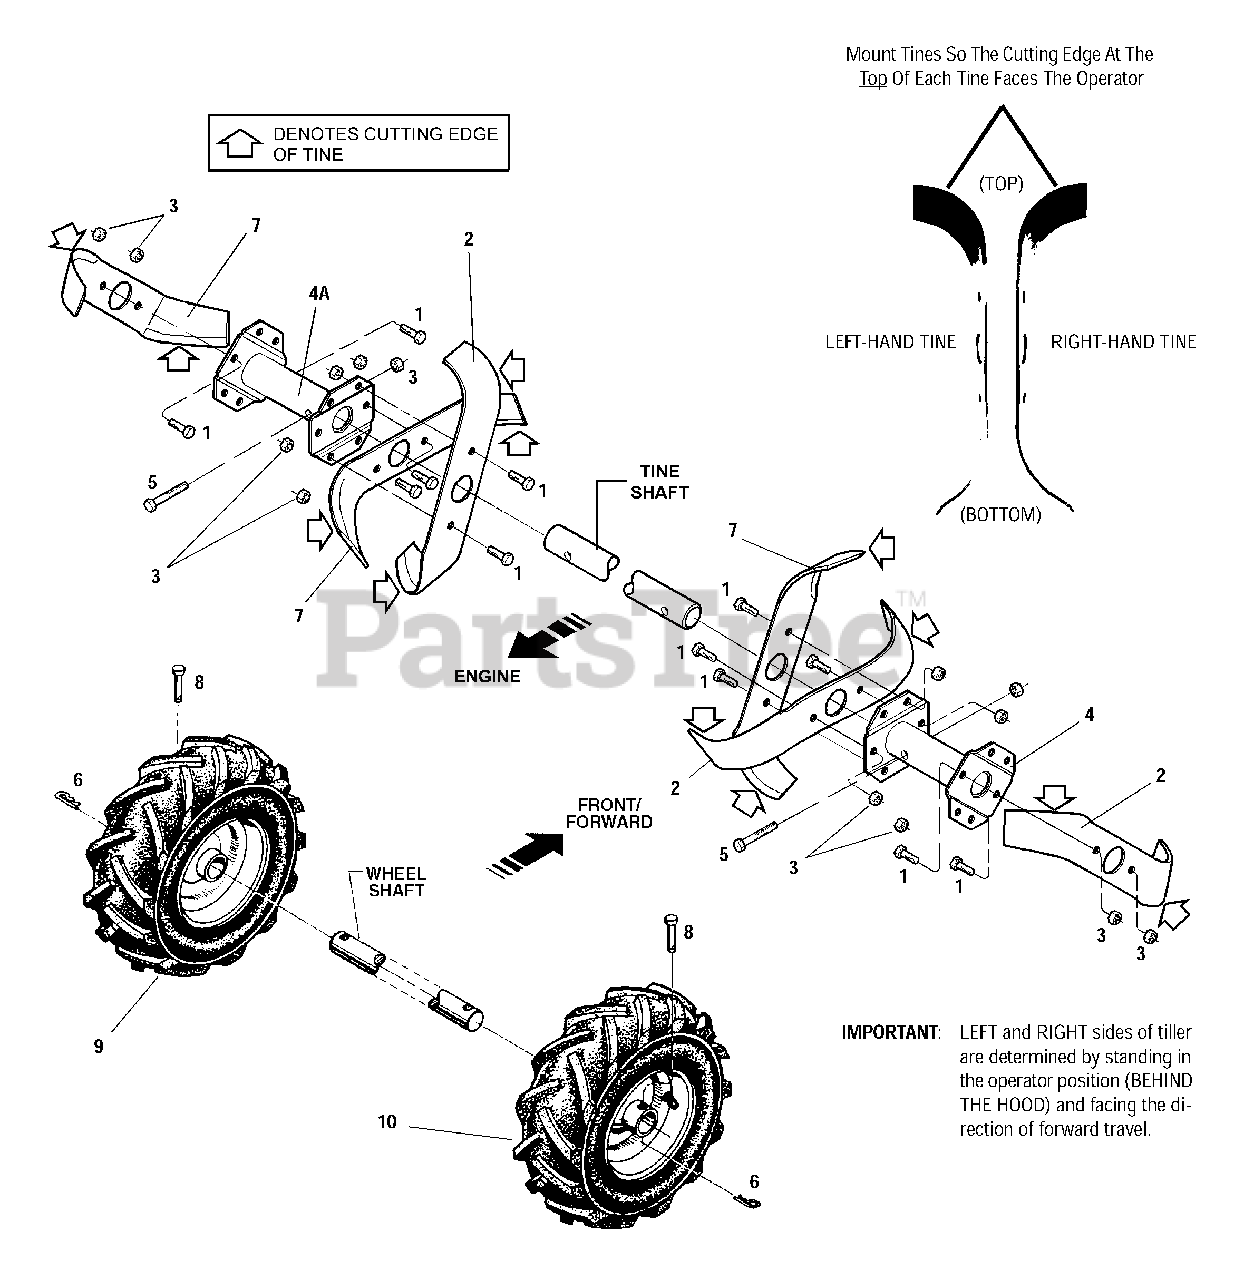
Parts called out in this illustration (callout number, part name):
1	Hex Hd. Screw, 3/8-16 x 3/4
2	Tine - right-hand
3	Hex Lock Nut, 3/8-16
4	Tine Holder, left-side
4A	Tine Holder, right-side
5	Hex Hd. Screw, 3/8-16 x 2, Grade 8
6	Hitch Pin
7	Tine - left-hand
8	Clevis Pin, .312 x 1-3/4 long
9	Wheel & Tire Assy., left-side
10	Wheel & Tire Assy., right-side
